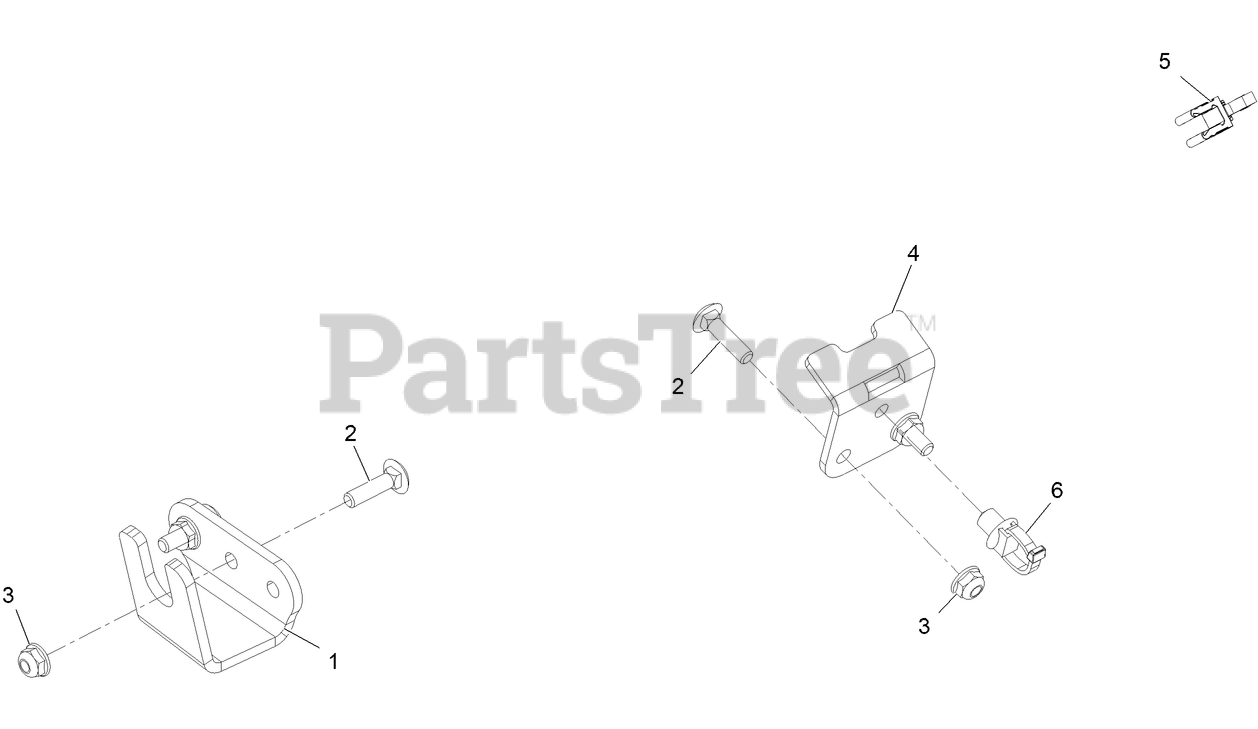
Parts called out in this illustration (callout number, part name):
1	BRKT-OCD CABLE
2	SCREW-CARR
4	BRKT-CABLE
5	Clip-Edge
6	CLIP-TIE
